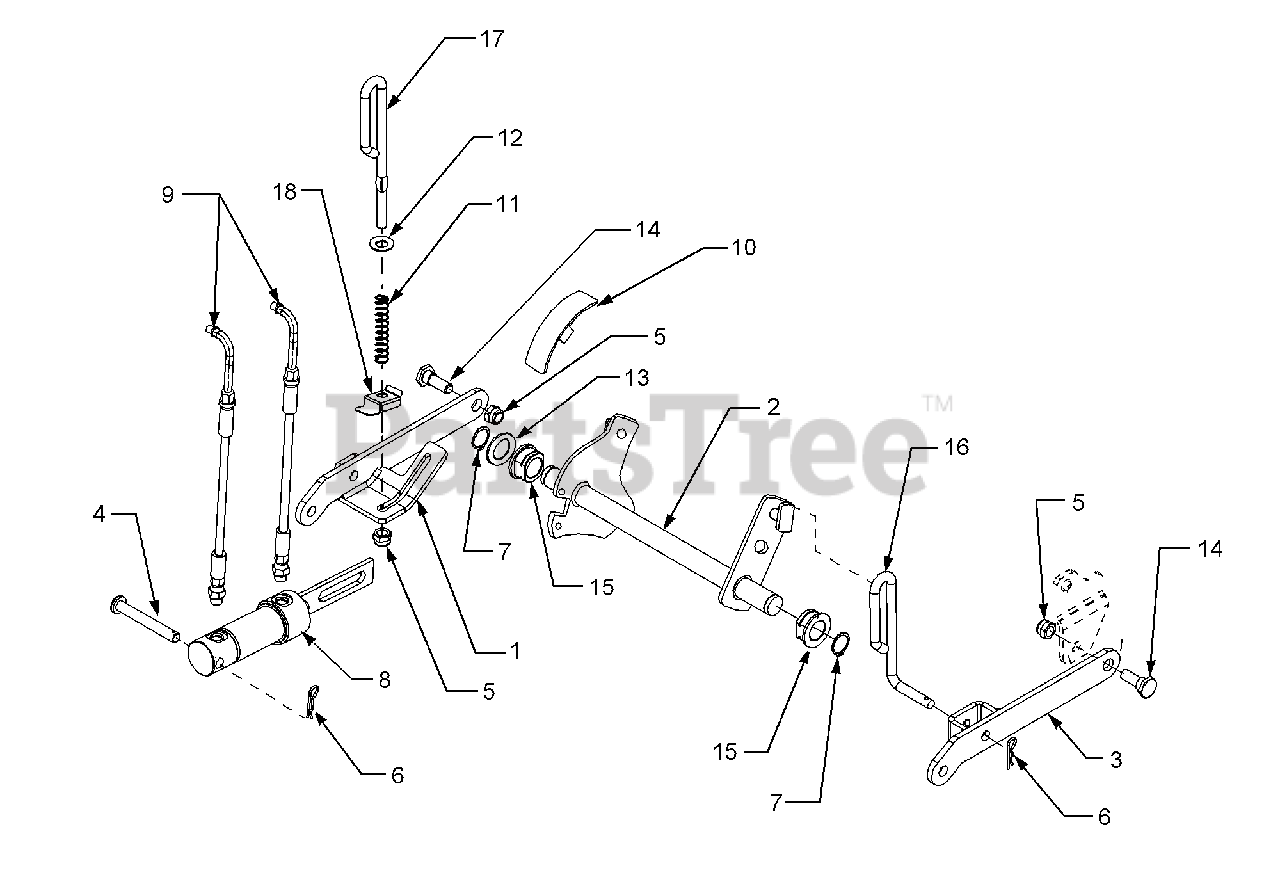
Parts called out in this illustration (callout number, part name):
5	Nut, Hex Lock, 1/2-13
6	Pin, Internal Cotter
7	Snap Ring, 1.0 Dia. Shaft
8	Cylinder, Center Lift
9	Hose, Lift
10	Indicator, Lift Position
11	Spring, Compression
12	Washer, Flat, .536 x .93 x .050
13	Washer. Flat, 1.0 x 1.7 x .10
14	Shoulder Screw
15	Bearing, Flange w/Flats
16	Rod, RH Lift
17	Rod, LH Lift
18	Stop Bracket, Lift Rod
